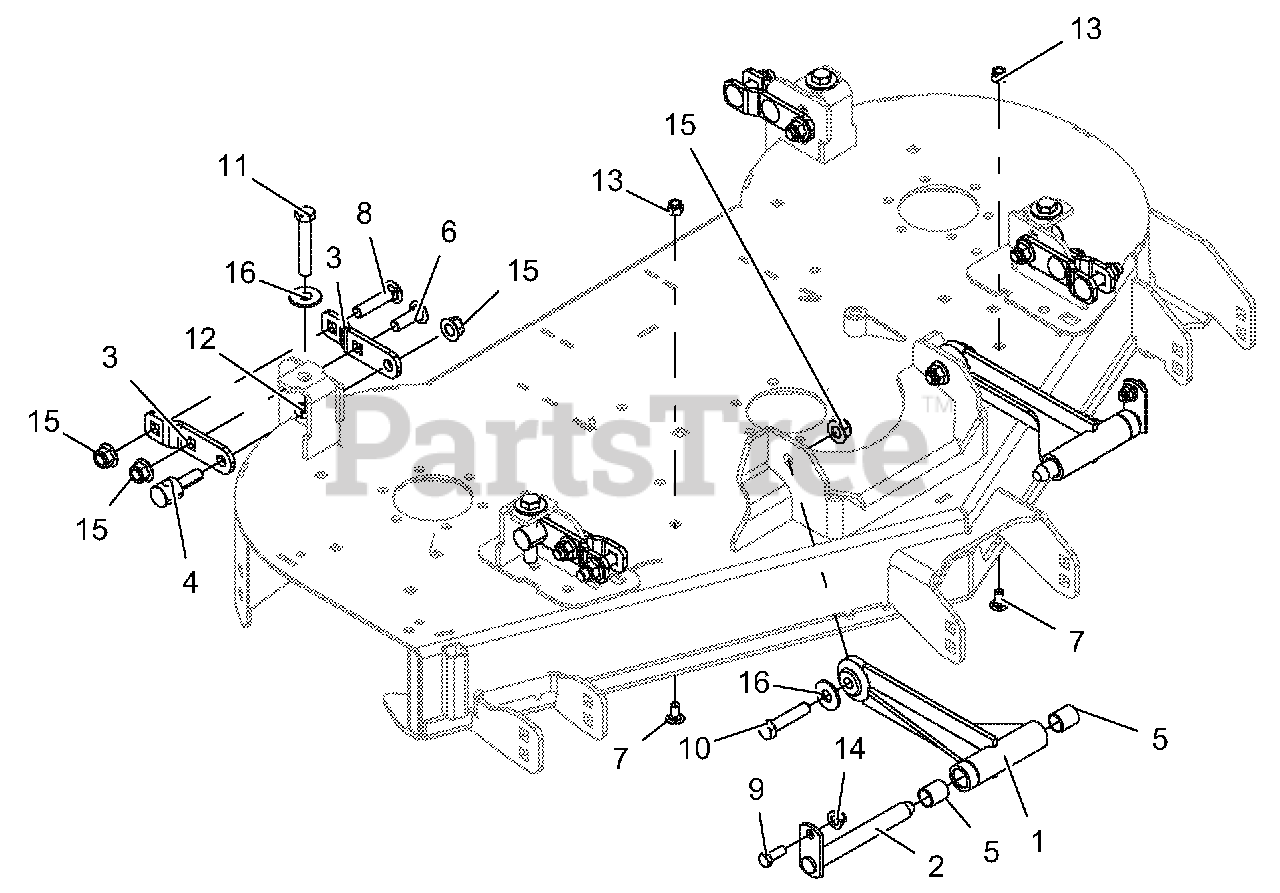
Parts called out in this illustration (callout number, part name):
1	WLDMT, DRAG LINK
2	WLDMT, MOWER MTG. PIN
3	BRKT, DECK LEVELING - BLACK
4	TRUNNION, .50-13
5	BRG, .75 X .875 X 1.00
6	BLT-RDHDSQNK .50-13 x 1.50 G5 YWZC
7	BLT-RDHDSQNK .38-16 x .75 G5 YWZC
8	BLT-RDHDSQNK .50-13 x 2.25 G5 Y
9	BLT-HEX .38-16 x 1.00 GR5 YWZC
10	BLT-HEX .50-13 x 2.25 GR5 YWZC
11	BLT-HEX .50-13 x 3.00 GR5 FTH YWZC
12	NUT, JAM .500-13 YWZC
13	NUT-LK-NYL .38-16 YWZC
14	NUT-LK-NYL-FLG .38-16 YWZC
15	NUT-LK-NYL-FLG .50-13 YWZC
16	WSHR-FL-STL .563 x 1.38 x .109 YWZC
